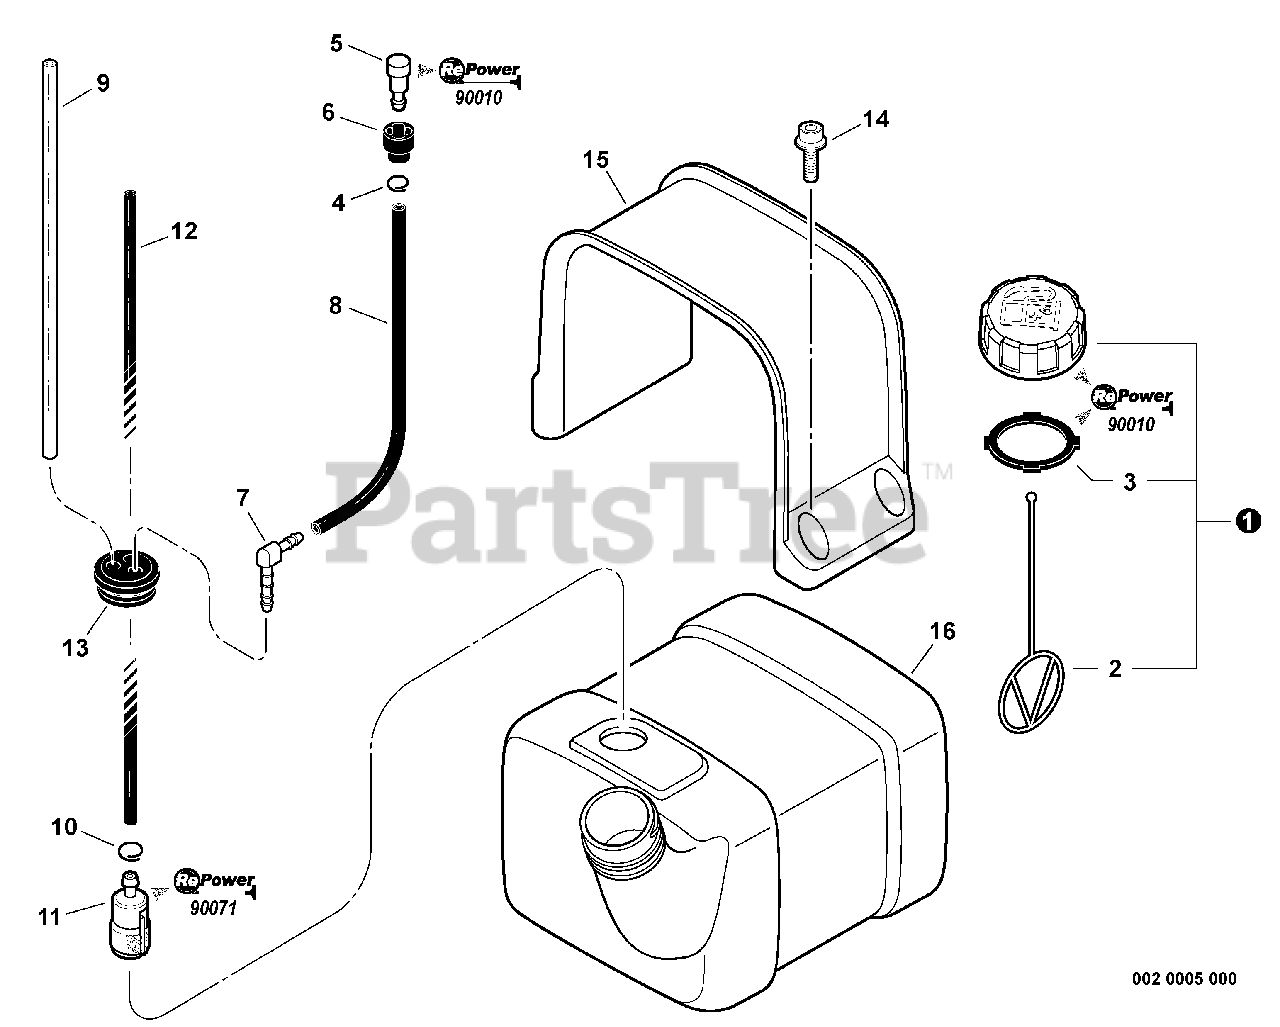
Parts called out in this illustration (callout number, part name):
1	CAP ASSY, FUEL
2	CONNECTOR, CAP L= 100 MM
3	GASKET, FUEL CAP
4	CLIP Ø6.5 MM
5	VENT ASSY
6	HOLDER, VENT
7	CONNECTOR, PIPE Ø5.4
8	PIPE, VENT 3×6×145 MM
9	PIPE, FUEL RETURN 3×6×145
10	CLIP Ø6.5 MM
11	FILTER, FUEL
12	PIPE, FUEL 3×6×230
13	GROMMET, FUEL
14	BOLT 5×14
15	BRACKET, FUEL TANK
16	TANK, FUEL
17	CAP/VENT KIT - REPOWER
18	TUNE-UP KIT - REPOWER
